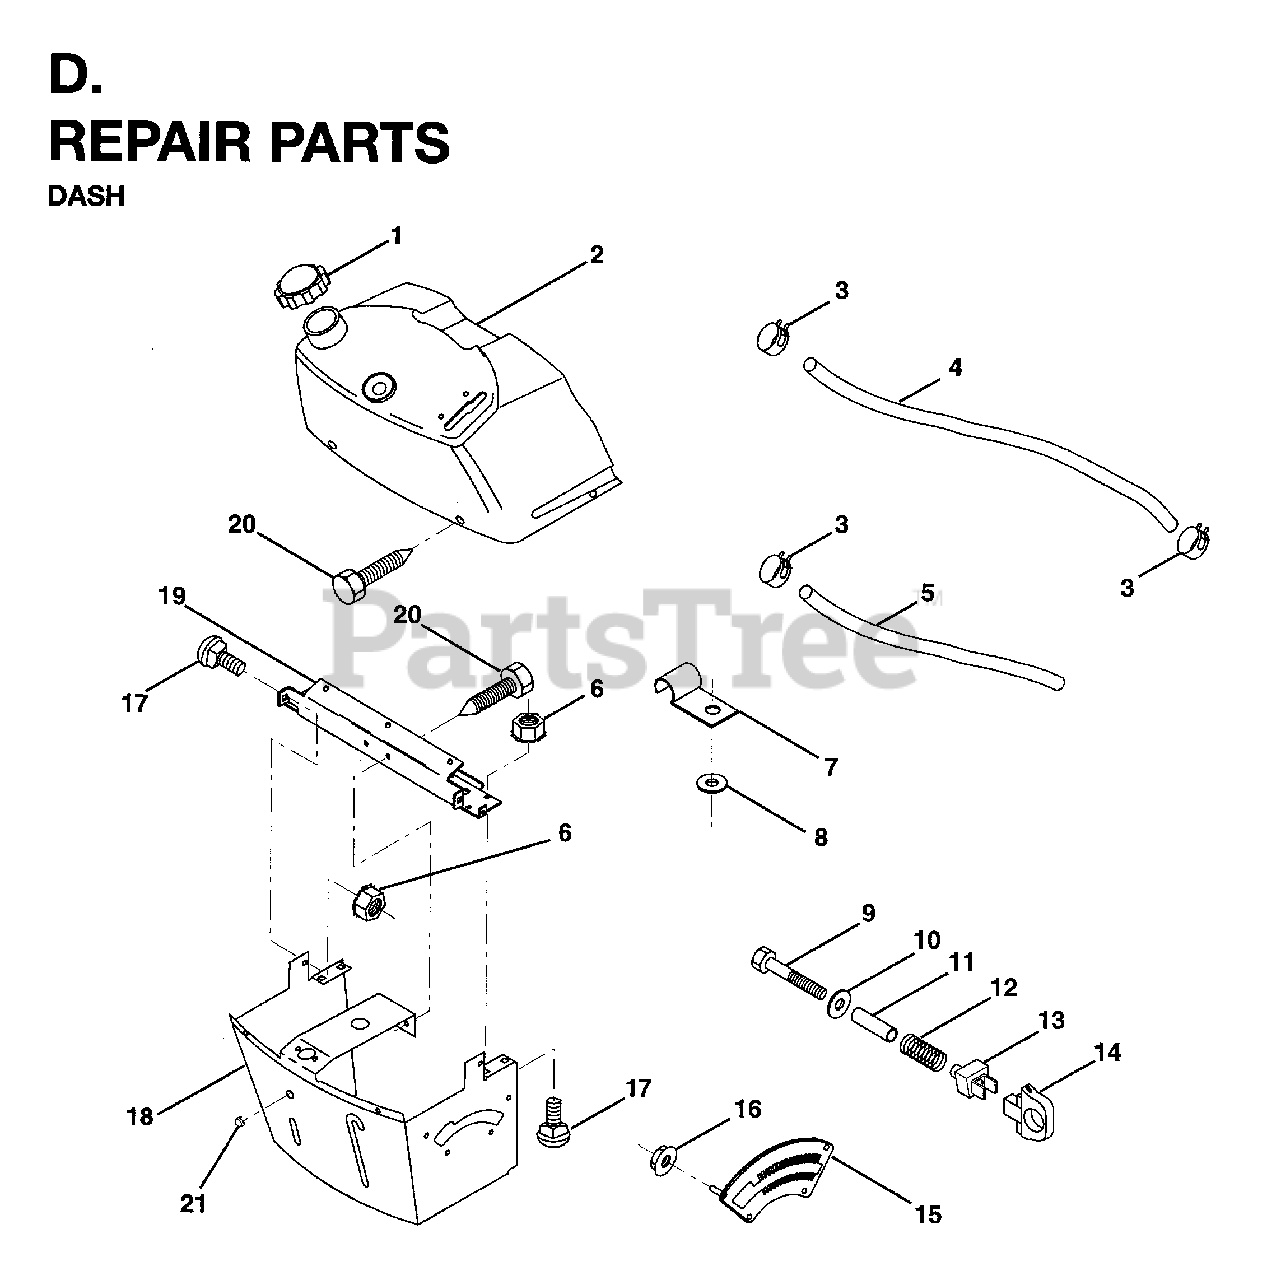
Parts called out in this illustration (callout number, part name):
3	HOSE CLAMP
4	FUEL LINE
5	FUEL LINE T
6	NUT.CROWNLOCK.1/4
7	CLIP T
8	WASHER - 26X6.5X1.6
9	BOLT HEX FIN 1/4-20X1 3/4
11	SPACER SPLIT
12	SPRING.COMPRESSION
13	KNOB HGT RETAINER
14	KNOB
15	ADJUSTER QUAD
18	SUPT ASSY DASH
19	CROSS BRACE
21	PLUG DOME
